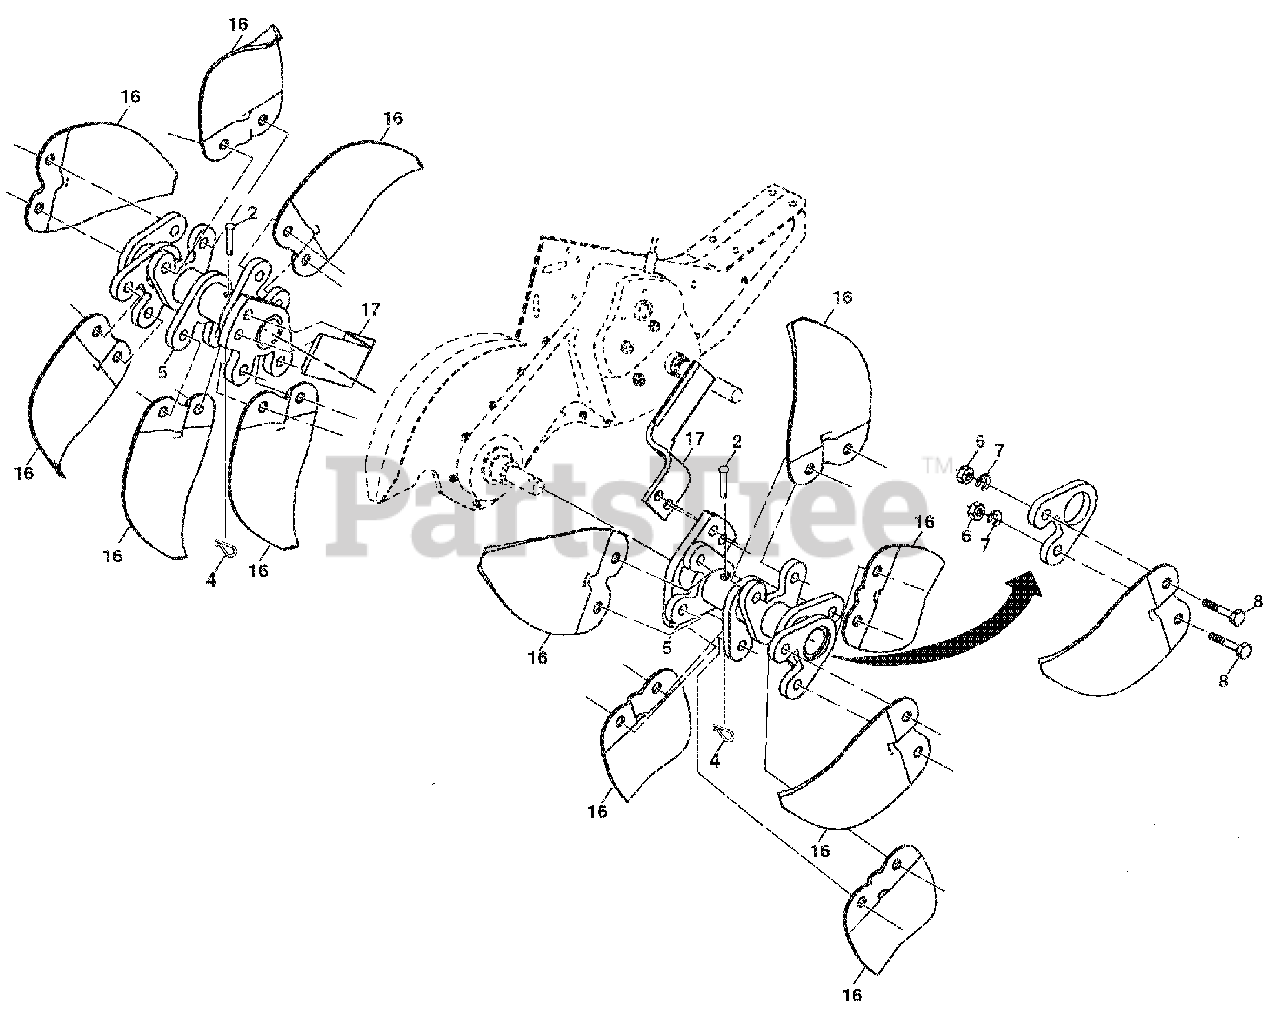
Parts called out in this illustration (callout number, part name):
2	Pin, Shear
4	Retainer, Spring
5	Tine Assembly
6	Nut, Hex 3/8-24
7	Washer, Lock 3/8
8	Bolt, Hex 3/8-24 x 1
16	Tine, Spade
17	Tine, Cleaning
